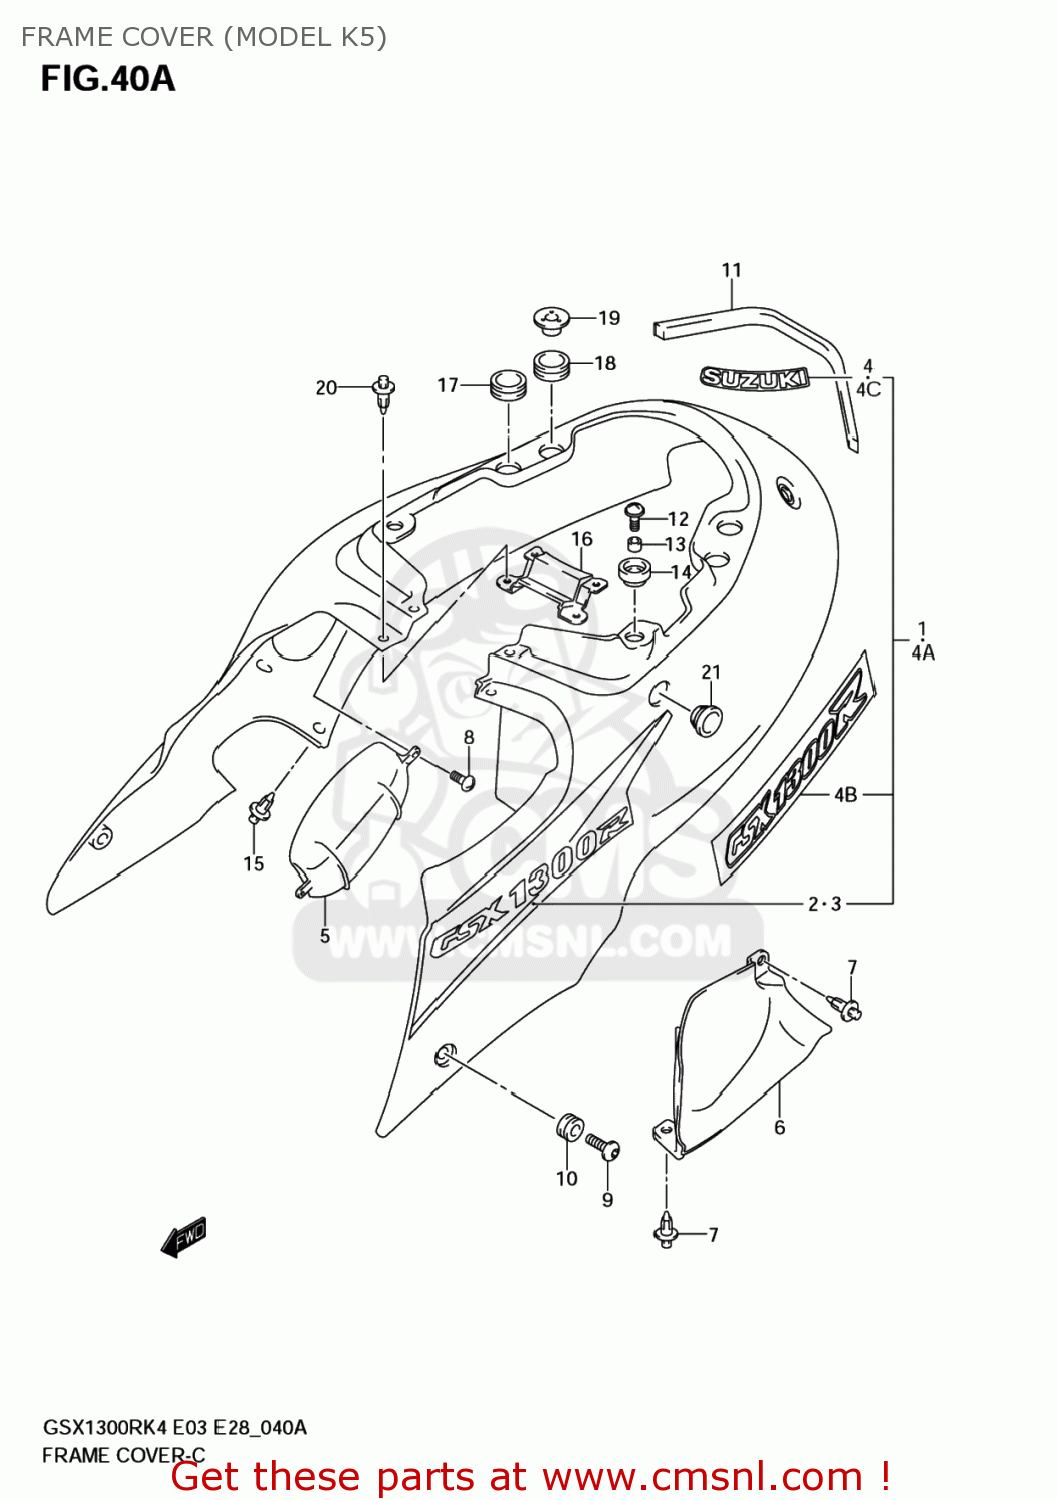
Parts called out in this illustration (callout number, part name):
1	COVER,FRAME(RED)
2	TAPE,FRAME COVER,R
3	TAPE,FRAME COVER,L
4	EMBLEM(GRAY)
4A	COVER,FRAME(GRAY)
4B	EMBLEM,FRAME COVER
4C	EMBLEM(GRAY)
5	CAP,FRAME COVER HOLE,R
6	CAP,FRAME COVER HOLE,L
7	CLIP(BLACK)
8	SCREW
9	SCREW(6X20)
10	CUSHION
11	CUSHION,FRAME COVER UPR
12	SCREW(6X20)
13	SPACER(6.5X10X11)
14	CUSHION
15	CLIP(BLACK)
16	COVER,FRAME CTR
17	CUSHION,FRAME COVER UPR RR
18	CUSHION,FRAME COVER UPR RR RR
19	WASHER,FRAME C
20	CLIP(BLACK)
21	CUSHION,FRAME COVER CTR
